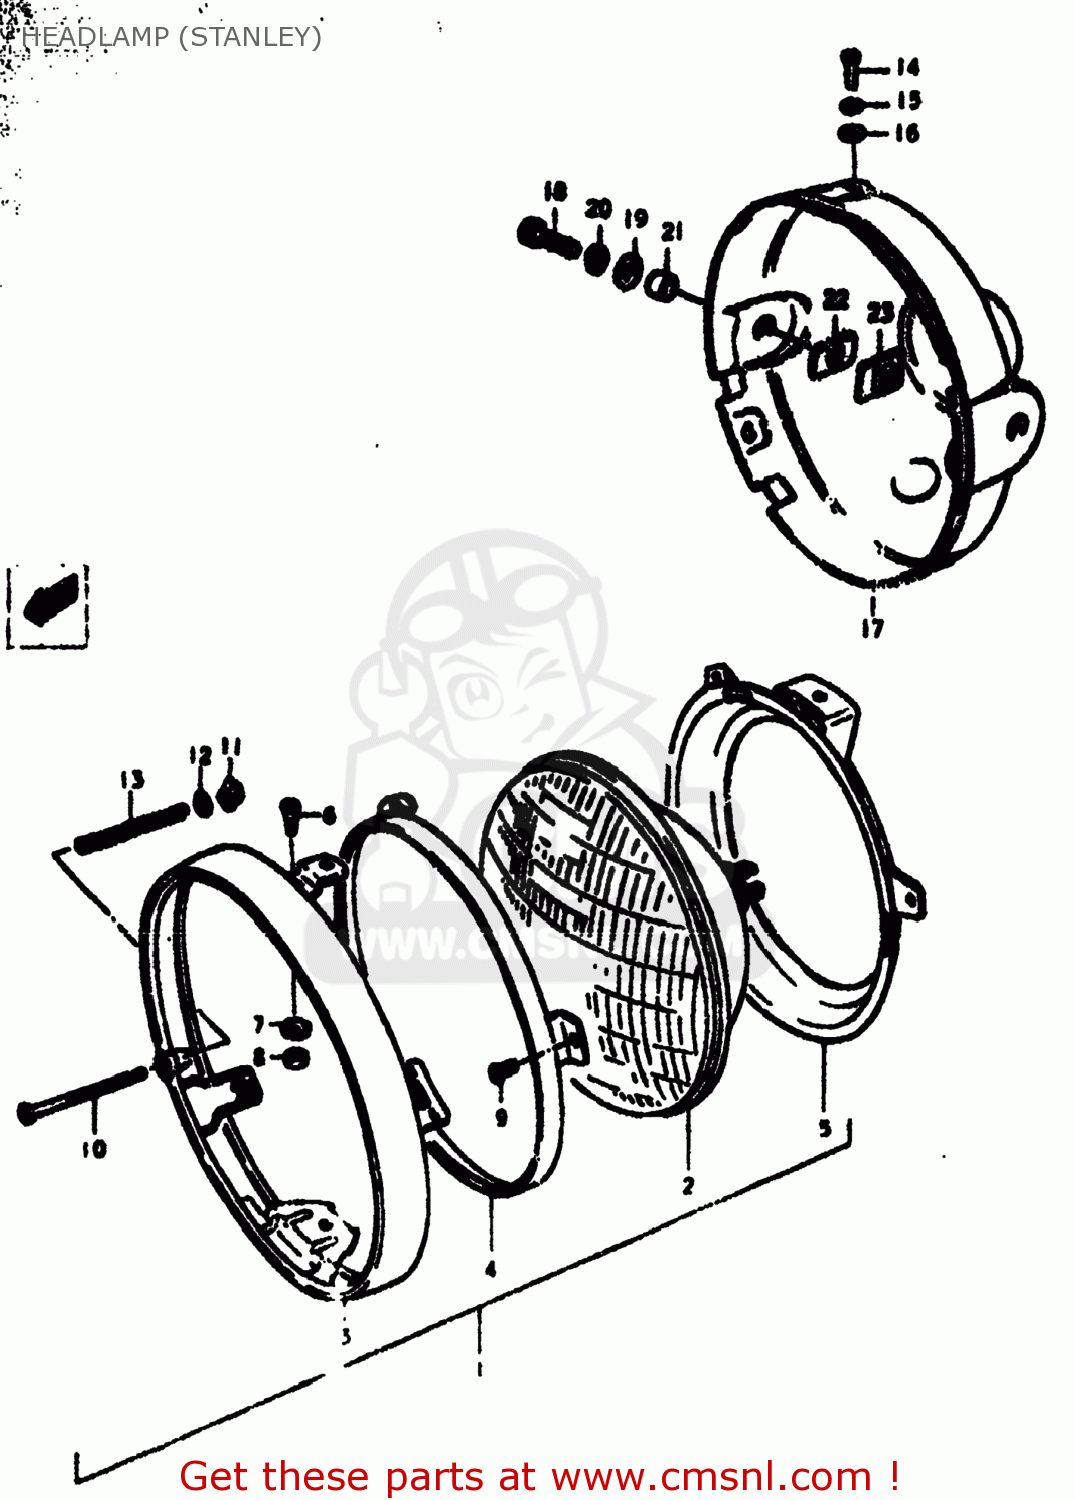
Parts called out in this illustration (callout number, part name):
1	HEADLAMP ASSEMBLY
2	LAMP UNIT
3	RIM
4	RETAINER
5	RING,HEADLAMP UNIT
6	SCREW
7	SPACER
8	NUT,ADJUSTING
9	SCREW
10	SCREW,HEADLAMP ADJUST
11	NUT
12	WASHER
13	SPRING,HEADLAMP ADJUST
14	SCREW
15	WASHER,LOCK
16	WASHER
17	HOUSING,HEADLAMP(BLACK)
18	BOLT
19	WASHER
20	LOCK WASHER
21	SPACER (8.8X12X7)
22	CUSHION
23	PLATE,HEADLAMP HOUSING
